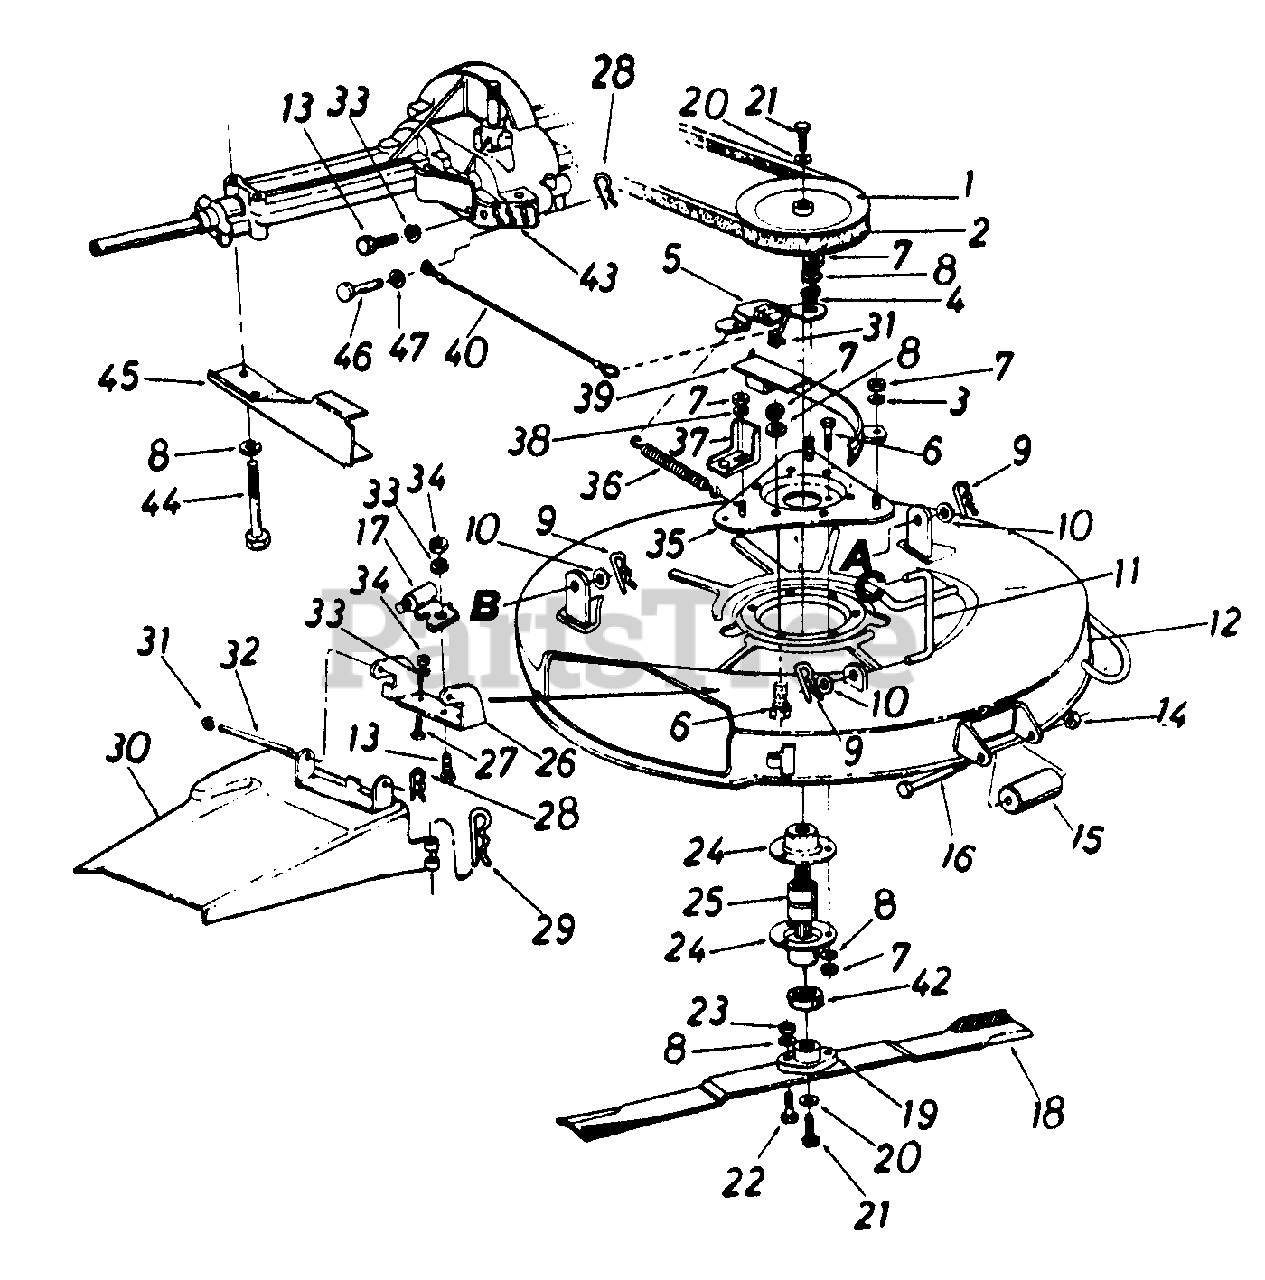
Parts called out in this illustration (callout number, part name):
1	Deck Pulley 7.00" O.D.
2	"V"-Belt 1/2" X 52" Lg.
3	Belleville Washer
4	Shoulder Spacer
5	Blade Brake Brkt. Ass'y.
6	Hex Bolt 5/16-18 x .75" Lg.
7	Hex Nut 5/1 61 8 Thd.
8	L-Wash. 5/16" I.D.
9	Intern. Cotter Pin 1/2" Dia.
10	Fl-Wash. .531" I.D. x .930"
11	Deck Link 3.9" Lg.
12	30" Deck Ass'y.
13	Hex Bolt 1/4-20 x .62" Lg.
14	Hex Nut 3/8-16 Thd.
15	Skid Roller
16	Shoulder Bolt .498" Dia. x 4.75"
17	Safety Switch
18	30" Blade
19	Blade Adapter
20	L-Wash. 3/8" I.D. H.D.
21	Hex Bolt 3/8-24 x .75" Lg.
22	Hex Bolt 5/16-24 x 1.00"
23	Hex Nut 5/16-24 Thd.
24	Housing Bearing Spindle
25	Blade Spindle
26	Deck Hinge Brkt.
27	Carriage Bolt 1/4-20 x .621'
28	Intern. Cotter Pin 5/16" Dia.
29	Cotter Pin
30	Chute Deflector Ass'y.
31	Cap Speed Nut 1/4" Rod
32	Hinge Pin
33	L-Wash. 1/4" I.D.
34	Hex Nut 1/4-20 Thd.
35	Spindle Mtg. Bracket Ass'y.
36	Extension Spring .38" O.D. x 3.25" Lg.
37	Belt Keeper Ass'y.
38	Belleville Wash. 5/16" I.D.
39	Belt Guard
40	Brake Cable Ass'y.
42	Bearing Guard
43	Lower Inside Belt Guard
44	Hex Bolt 5/16-18 x 2.75"
45	Lower Outside Belt Guard
46	Clevis Pin 1/4" X 1/2"
47	Fl-Wash. 1/4" I.D. x .50" O.D.
